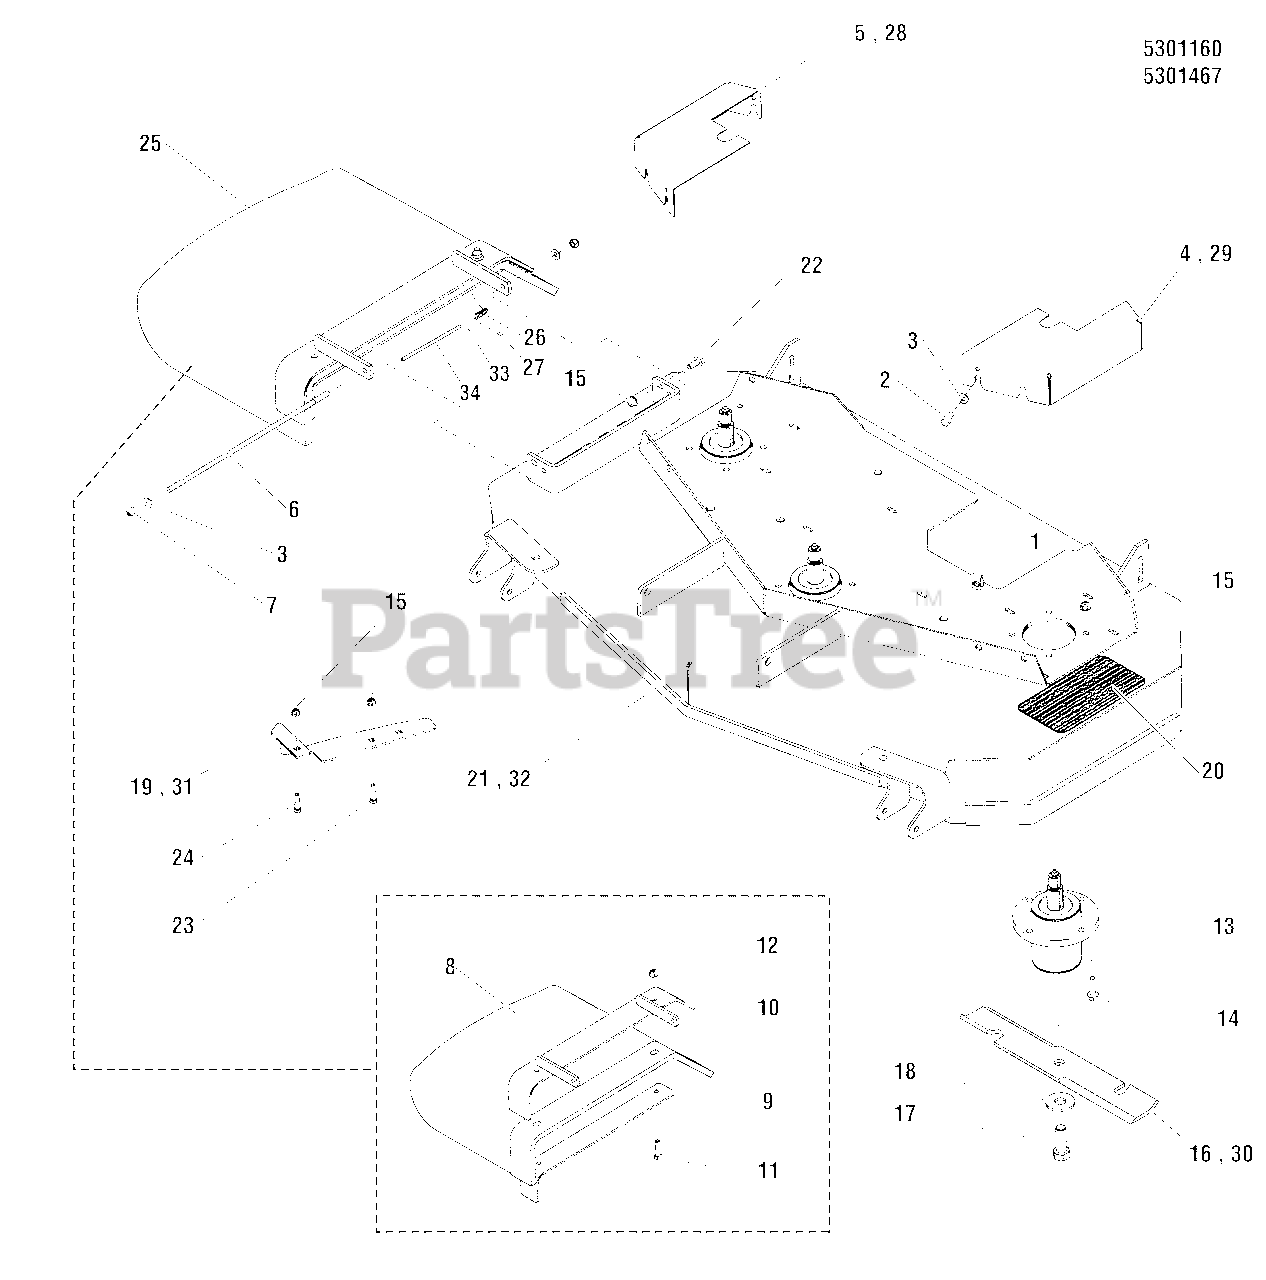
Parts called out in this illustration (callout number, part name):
1	BODY CLIP, 5/16-18 X 1/2 DEEP
2	BOLT, 5/16-18 X 3/4 GD5
3	WASHER, 5/16 SAE
4	GUARD, 44" MOWER DECK, LH - ORG
5	GUARD, 44" MOWER DECK, RH - ORG
6	ROD, BRAKE LINKAGE
7	NUT, 5/16-24 HEX NYLON LOCK
8	CHUTE, DISCHARGE, RUBBER, 44/48/52
9	SUPPORT, DISCHARGE CHUTE, 48/52 - BLK
10	WELD, FRAME CHUTE, 44/48/52 - BLK
11	BOLT, 3/8-16 X 1-1/2 GD5 YZ
12	NUT, 3/8-16 HEX NYLOCK FLANGE
13	ASSM, SPINDLE, LOW PROFILE
14	BOLT, 5/16-18 X 1 1/4 FLANGE
15	NUT, 5/16-18 HEX NYLOCK FLANGE
16	BLADE, 15" (SET OF THREE)
17	BOLT, 5/8-11 X 1-3/4" GD8
18	WASHER, 5/8 USS
19	WELD, DISCHARGE BAFFLE, 44" - BLK
20	SAFETY WALK, 4.00 X 7.50
21	DECK SHELL W/DECALS, 44, IS500Z (SV)
22	SCREW-HEX WZ LOCK FLNG 5/16-18X0.750BLK
23	BOLT, 5/16-18 X 1, CARRIAGE
24	BOLT, 5/16-18 X 3/4", CARRIAGE
26	SPRING, TORSION
27	CAP, PROTECTOR, .120 ID
28	GUARD, DECK, RH
29	GUARD, DECK, LH
30	BLADE, 16.25 X.25 X 2.5, 1 X 3.5 (SET OF 3)
31	PLATE, DEFLECTOR - BLK
32	DECK SHELL W/DECALS, 48, ZT4000 (SV)
33	WASHER, 5/16 FENDER
34	TUBE, 1/2 X 3/8 BLACK POLY, 8.00 LG
